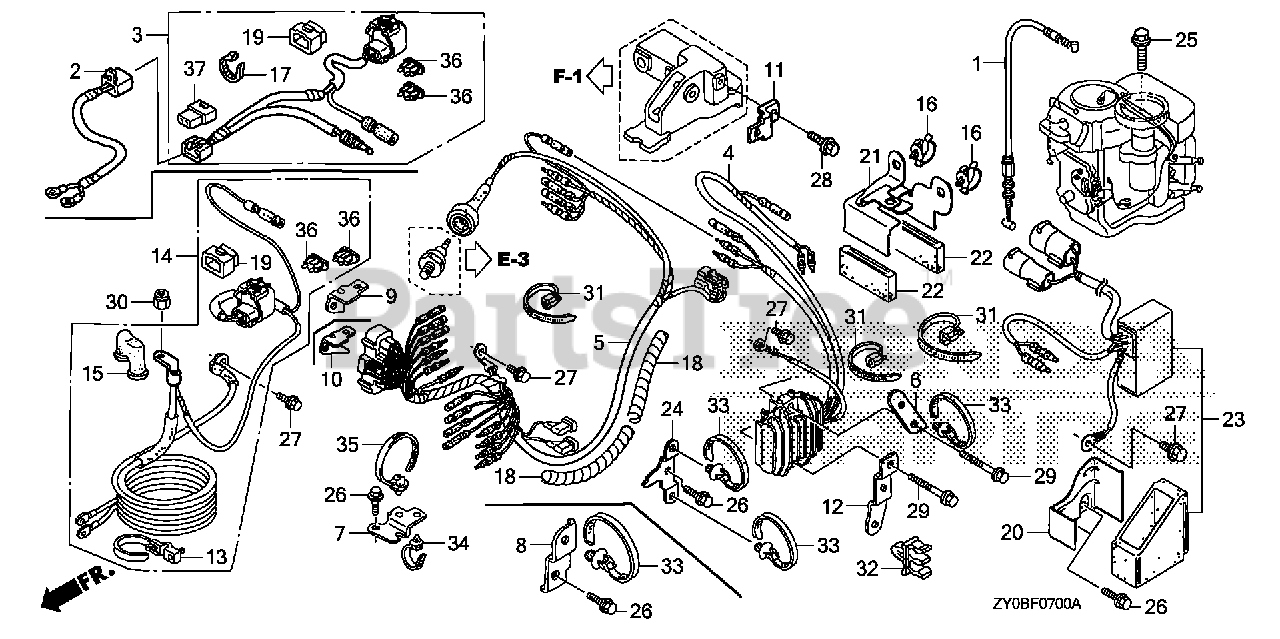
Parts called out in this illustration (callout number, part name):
1	CABLE, NEUTRAL STARTING
2	WIRE ASSY., BATTERY CHARGE
3	RECEPTACLE ASSY., CHARGE
4	RECTIFIER ASSY., REGULATOR
5	WIRE HARNESS ASSY.
6	BRACKET, CLIP F
7	BRACKET, STARTER CABLE
8	BRACKET, CLIP B
9	BRACKET, FUSE CASE
11	BRACKET, CONNECTOR D
12	BRACKET, E-CLIP
17	TIE, CABLE (2.4X92) (NATURAL)
18	TUBE, SPIRAL A
19	COVER ASSY., FUSE (20A)
25	BOLT, FLANGE (6X20)
26	BOLT, FLANGE (6X14) (CT200)
27	BOLT, FLANGE (6X12)
28	BOLT, FLANGE (6X12)
29	BOLT, FLANGE (6X26) (CT200)
31	TIE, CABLE
32	CLIP, FUEL TUBE
33	CLIP, HARNESS BAND (151.5MM) (NATURAL)
35	BAND, WIRE HARNESS (93.5MM) (WHITE)
36	FUSE, BLADE (20A)
37	CONNECTOR, DUMMY
